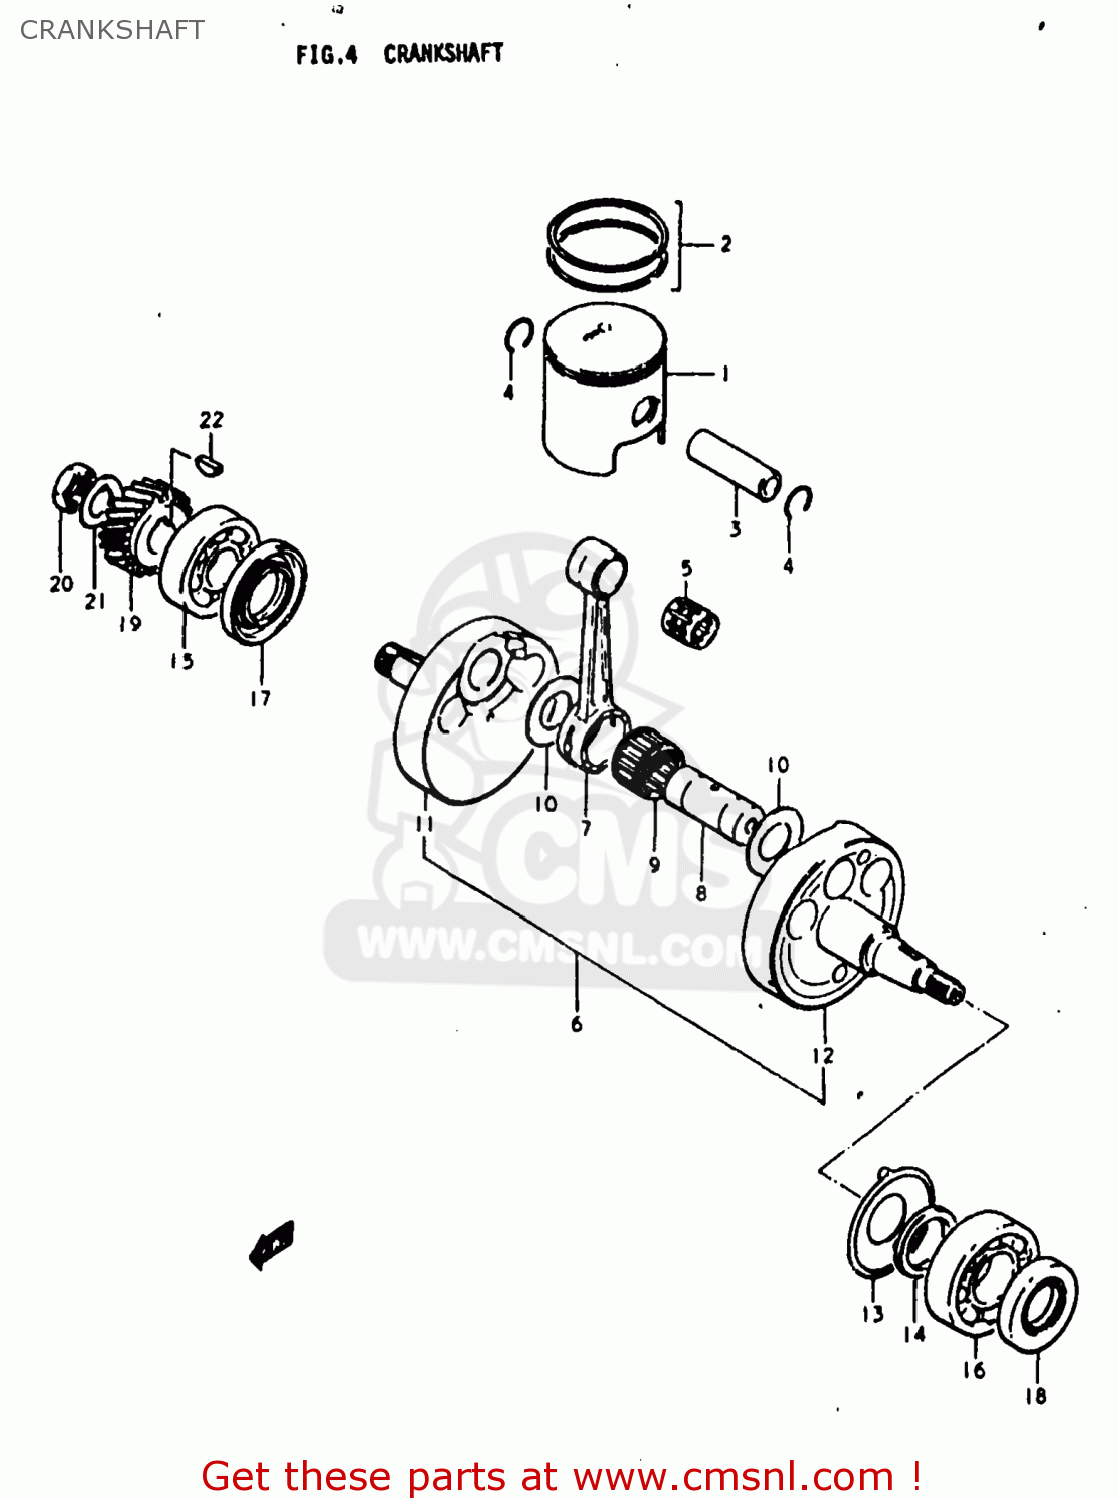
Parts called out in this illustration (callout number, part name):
1	PISTON
2	RING SET,PISTON
3	PIN,PISTON (18MM)
4	CIRCLIP
5	BEARING
6	CRANKSHAFT ASSEMBLY
7	ROD,CONNECTING
8	PIN,CRANK
9	BEARING(25X31X20)
10	WASHER(25X40X1)
11	CRANKSHAFT,RIGHT
12	CRANKSHAFT,LEFT
13	PLATE,CRANKSHAFT OIL GUIDE
14	SPACER (30X45X4.8)
15	BEARING
16	BEARING(30X72X19)
17	SEAL,OIL(35X62X9)
18	OIL SEAL
19	GEAR,PRIMARY DRIVE
20	NUT
21	WASHER
22	KEY
